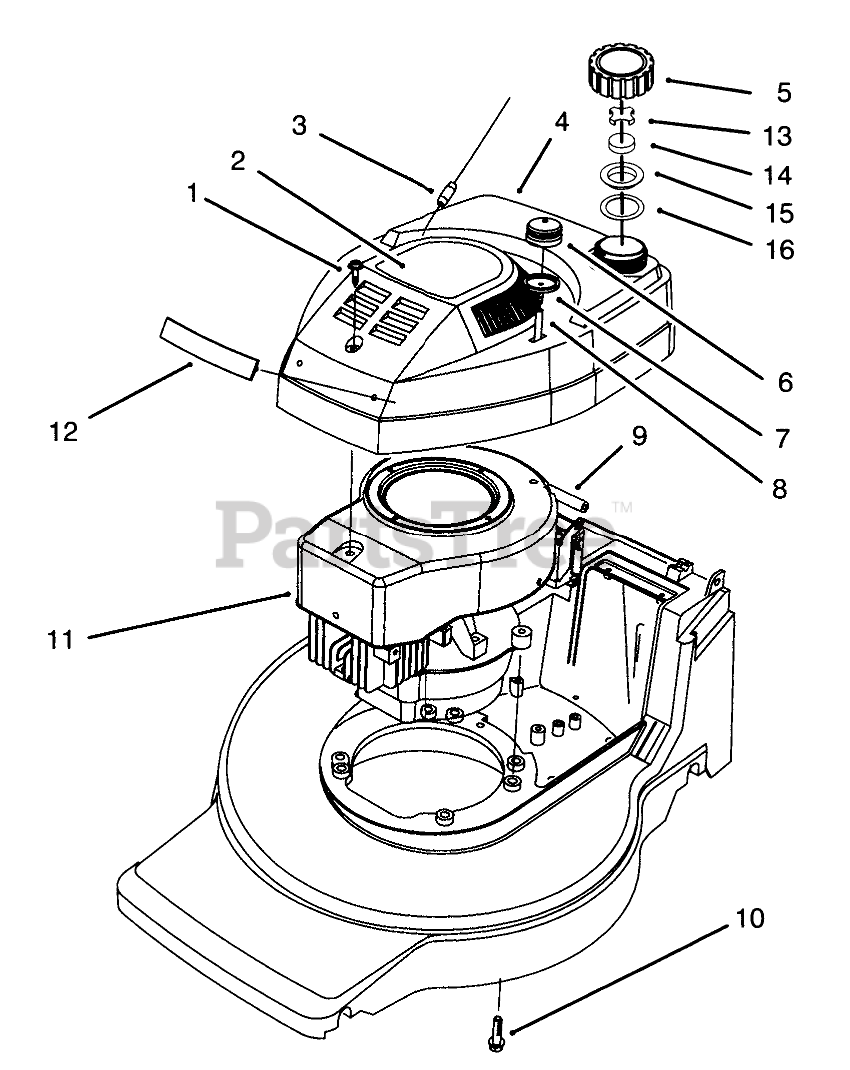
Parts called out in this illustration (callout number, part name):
1	Engine Assembly
2	FILTER-FUEL
3	NUT-LOCK, CONE
4	WASHER-PLAIN
5	Screw
6	CAPSCREW
7	WASHER-LOCK
8	WASHER-CLUTCH
9	CLUTCH/BRAKE
10	V-BELT, DRIVE
11	SPACER-LOWER
12	Adapter-Crankshaft
13	CRANKSHAFT KEY
14	Pulley-Drive
15	UPPER SPACER
16	Retainer-Clutch
17	CAPSCREW
18	ENGINE PLATE
19	DECAL
20	JLO WIRE HARNESS
21	DECAL
22	Module
